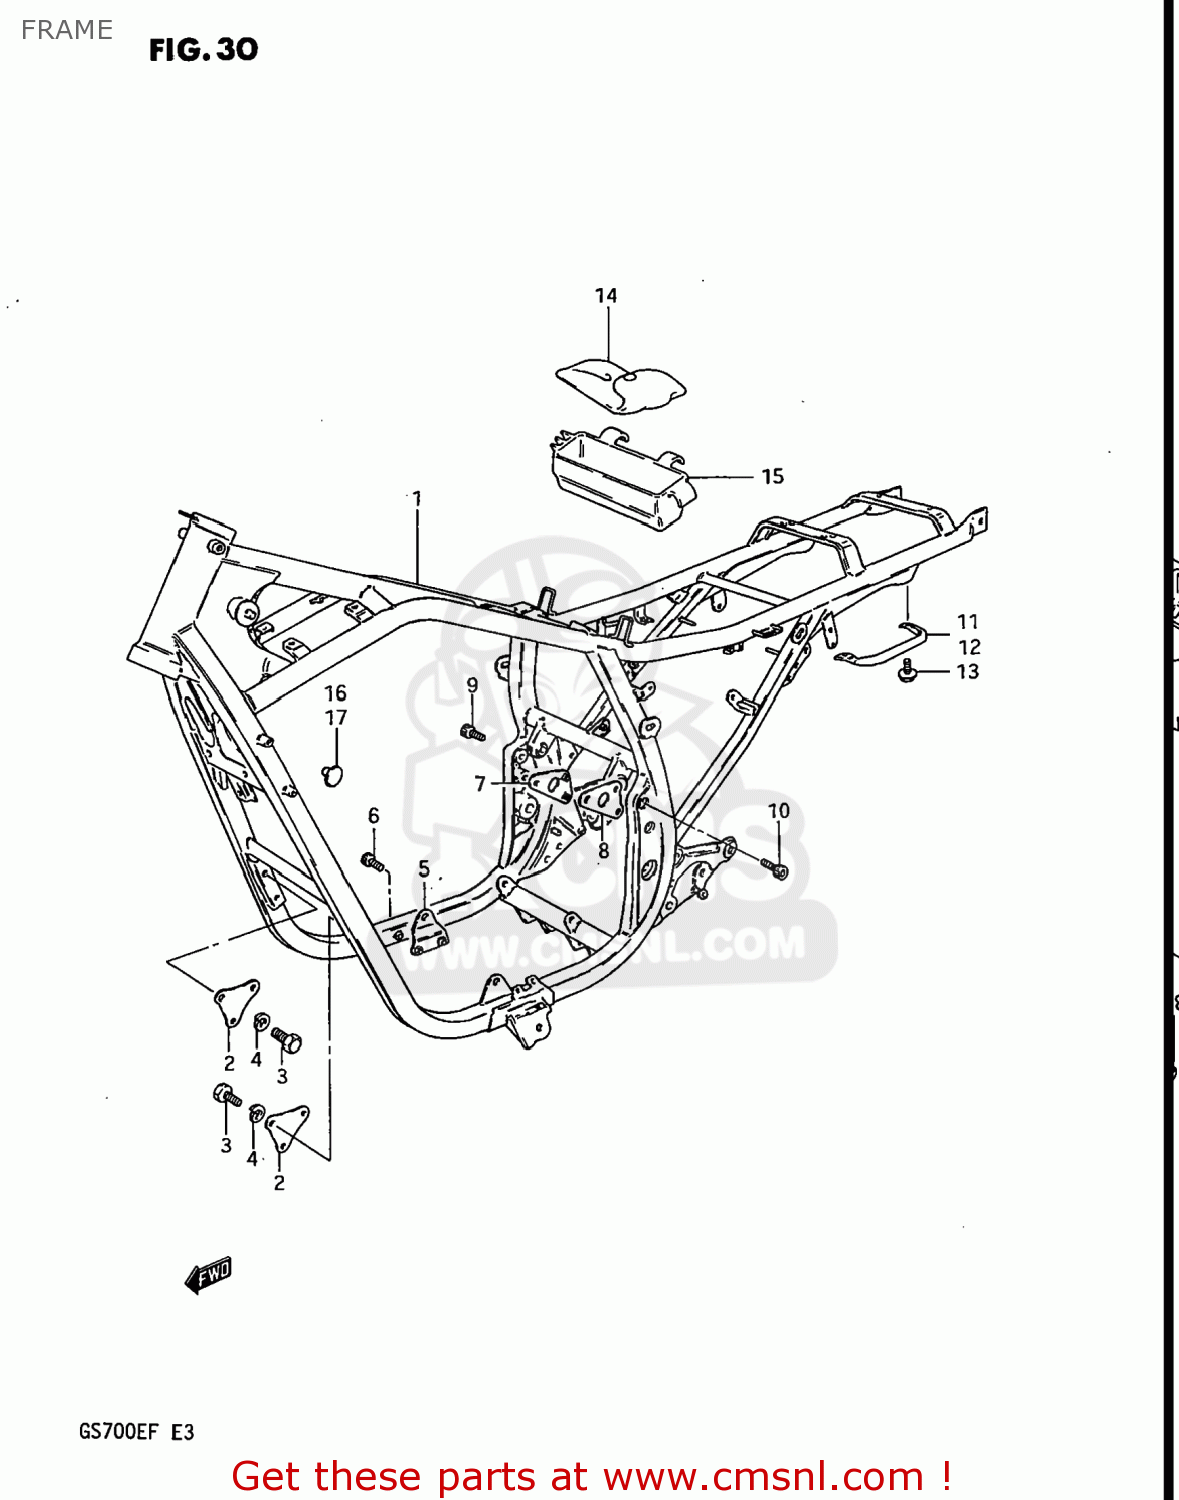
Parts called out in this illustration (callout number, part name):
1	FRAME
2	PLATE,ENGINE MOUNTING NO
3	BOLT
4	WASHER,LOCK,8.
5	PLATE,ENGINE MOUNTING NO
6	BOLT
7	PLATE,ENGINE MOUNTING NO
8	PLATE,ENGINE MOUNTING NO
9	BOLT 8X35
10	BOLT
11	GRIP,FRAME HANDLE,RIGHT
12	GRIP,FRAME HANDLE,LEFT
13	BOLT, LOWER
14	TOOL SET
15	HOLDER,TOOL
16	PLUG(OD:12)
17	PLUG(OD:12)
